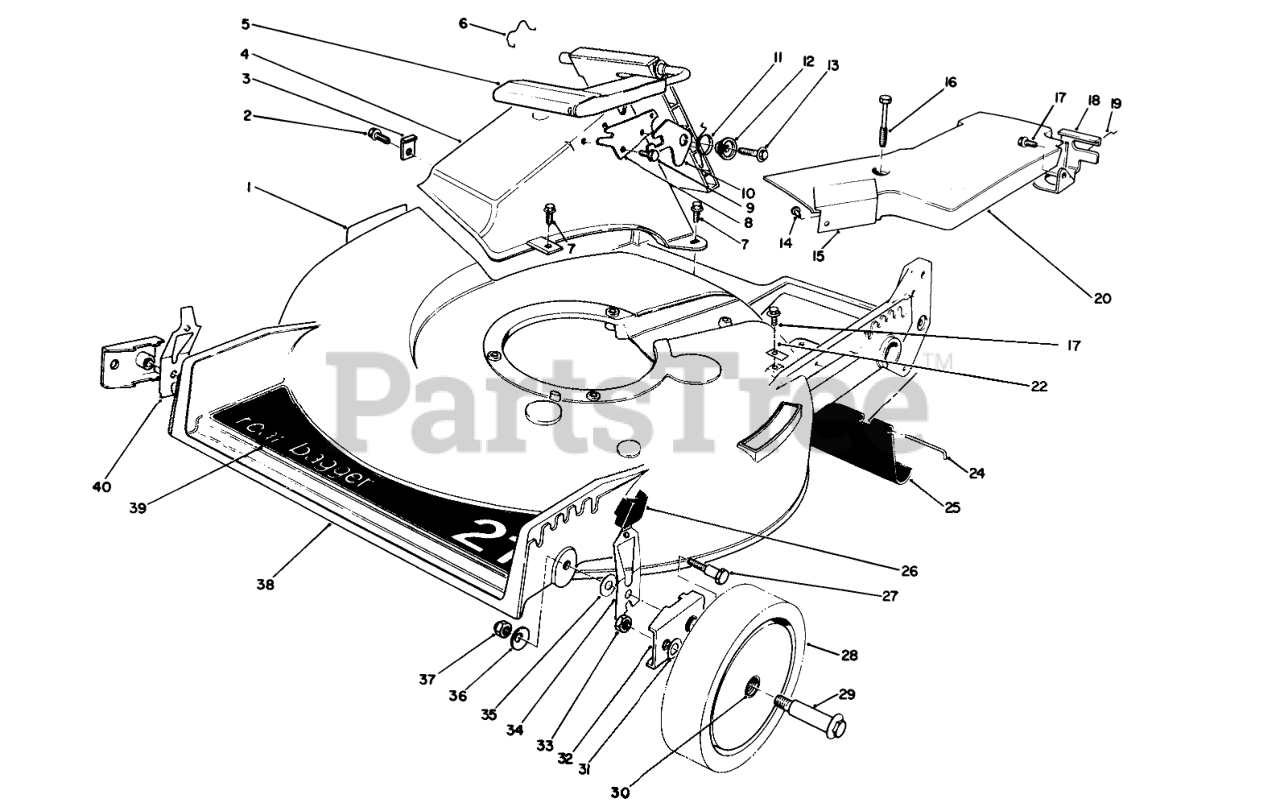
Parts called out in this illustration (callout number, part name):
1	DECAL-DANGER
2	SCREW
3	TUNNEL CLIP
4	Tunnel-Discharge (Incl. Ref. #1)
5	Discharge Door Assembly
6	DOOR RET SPRING
7	SCREW-HWH
8	DOOR LATCH PLATE
9	SCREW-PLASTITE
10	SAFETY LATCH
11	TORSION SPRING
12	DOOR SPACER
13	SCREW-HWH
14	RIVET-HEAD, FLAT
15	HEAT SHIELD
16	SCREW-HHFTF
17	SCREW-HWHTF
18	Bracket-Traction Adj.
19	RETAINER-CABLE
20	Belt Cover Assembly (Incl. Ref. #14& 15)
22	CLAMP-CABLE
24	ROD-SHIELD
25	SHIELD-TRAILING
26	KNOB-ARM
27	PIVOT SCREW
28	Wheel & Tire Assembly (Incl. Ref. #30)
29	BOLT-WHEEL
30	BUSHING
31	WASHER
32	HP PIVOT ARM ASM
33	Nut
34	L. HP SPRING ARM ASM
35	WASHER-PIVOT
36	WASHER-BELLEVILLE
37	NUT-LOCK, NI
38	Housing (Incl . Ref . #1)
39	DECK DECAL
40	R HP SPRING ARM ASM
